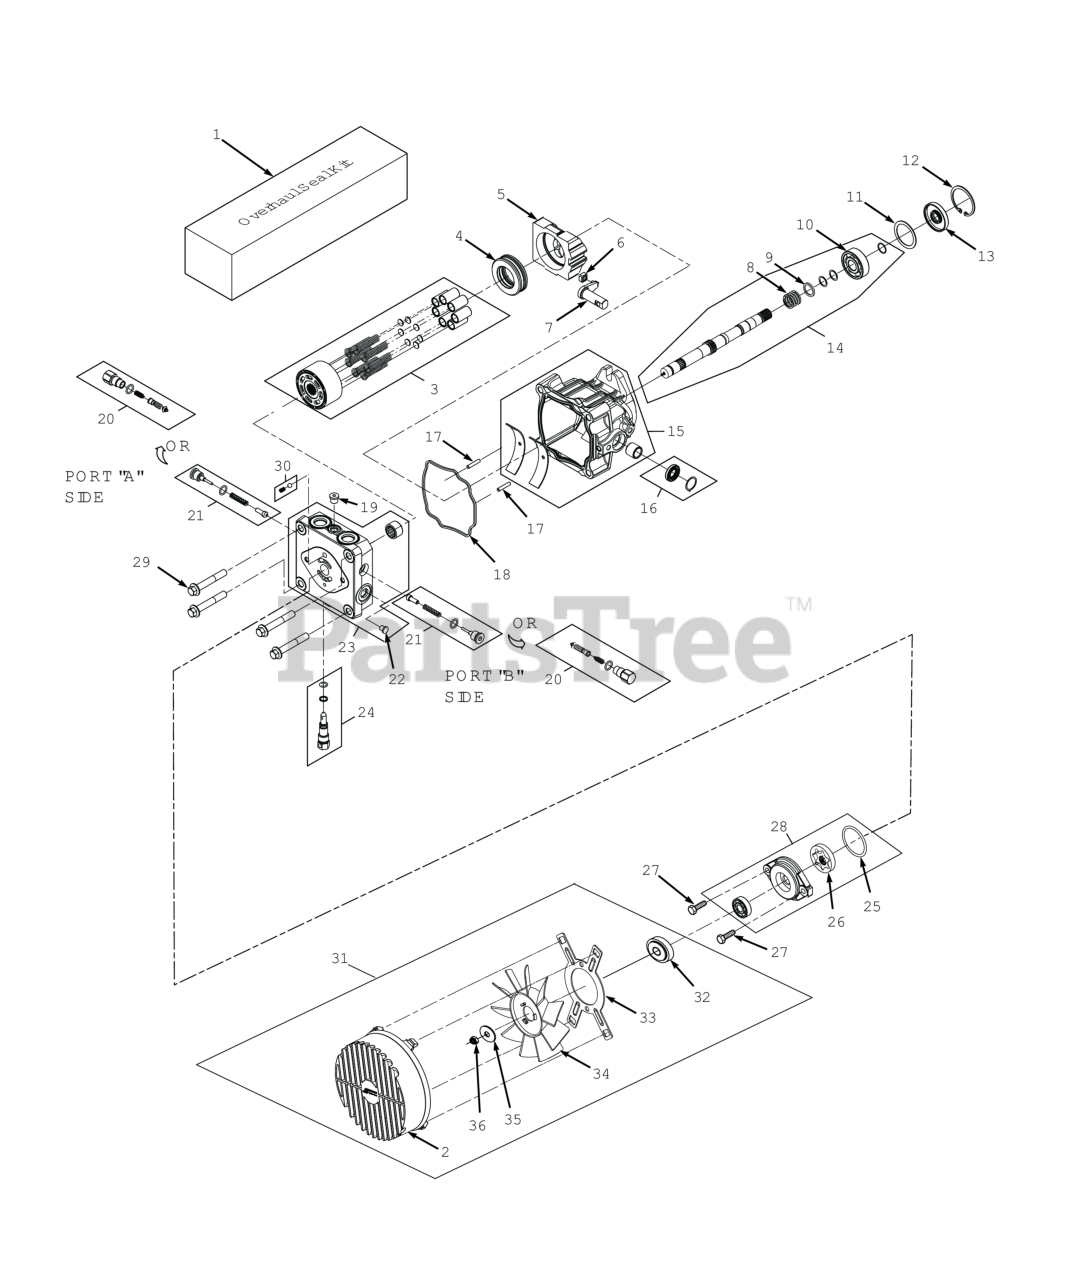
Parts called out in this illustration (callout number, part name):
1	Overhaul Seal Kit
2	Fan Cover
3	Cylinder Block Kit - 16cc
4	Thrust Ball Bearing Assembly
5	Variable Swashplate
6	Slot Guide
7	Trunnion Arm
8	Spring Block
9	Block Thrust Washer
10	Shaft Ball Bearing
12	Retaining Ring
13	Lip Seal
14	Kit, Pump Shaft (keyed thru taper)
15	Housing Kit
16	Trunnion Seal Kit
17	Straight Headless Pin
18	O-Ring
19	Straight Thread Plug
20	System Check Relief Kit, port "B" on Left Hand Pump, port "A" on Right Hand Pump
21	Shock Valve Kit (.024" Orifice)
22	Straight Thread Plug
23	End Cap Kit
24	Bypass Valve Kit
25	O-Ring, Charge Pump Cover
26	Gerotor Assembly (.19 cu.in./rev.)
27	Socket Head Cap Screw (M8 x 1.25-25mm)
28	Charge Pump Kit (.19 STD. Splined)
29	Hex Screw, Flanged Head (M10 x 1.50-65mm)
30	Charge Relief Valve Kit
31	Fan Kit
32	Washer
33	Bracket, Shroud
35	Washer
